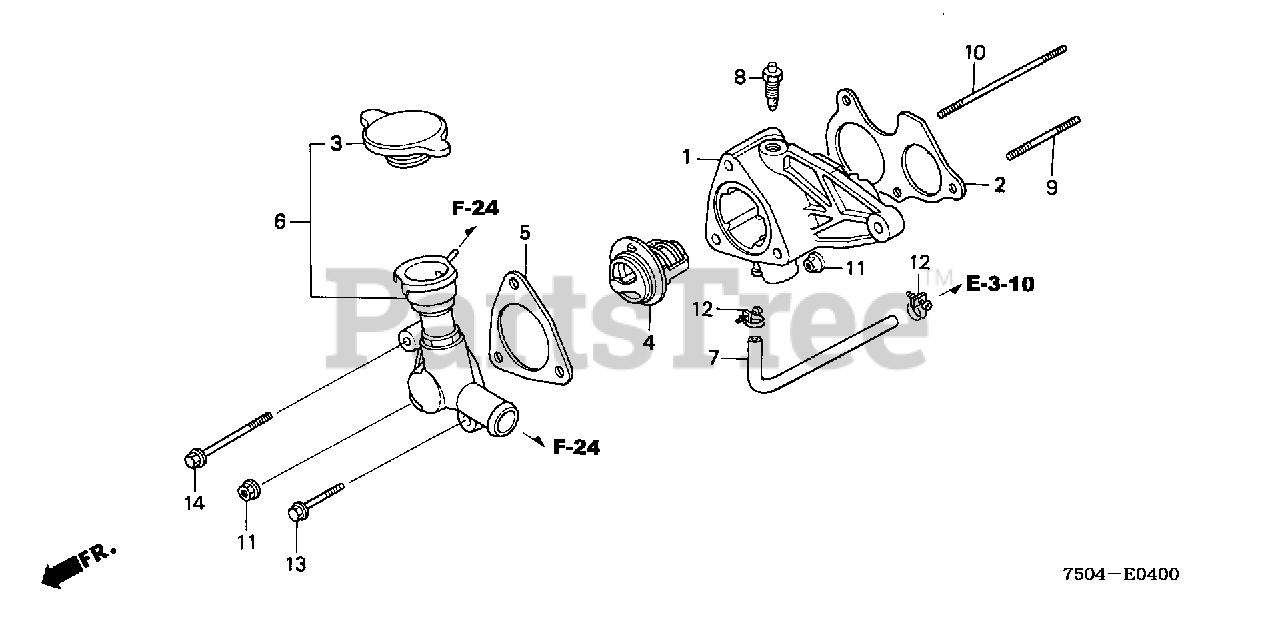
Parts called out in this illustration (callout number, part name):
1	CASE, THERMOSTAT
2	GASKET, GOVERNOR CASE
3	CAP, RADIATOR (DENSO)
4	THERMOSTAT ASSY.
5	GASKET, THERMOSTAT COVER
6	COVER, THERMOSTAT
7	HOSE, WATER BYPASS
8	BOLT, BREATHING WATER
9	BOLT, STUD (6X25)
10	BOLT, STUD (6X60)
11	NUT, FLANGE (6MM)
12	CLIP, TUBE (A13)
13	BOLT, FLANGE (6X65)
14	BOLT, FLANGE (6X90)
